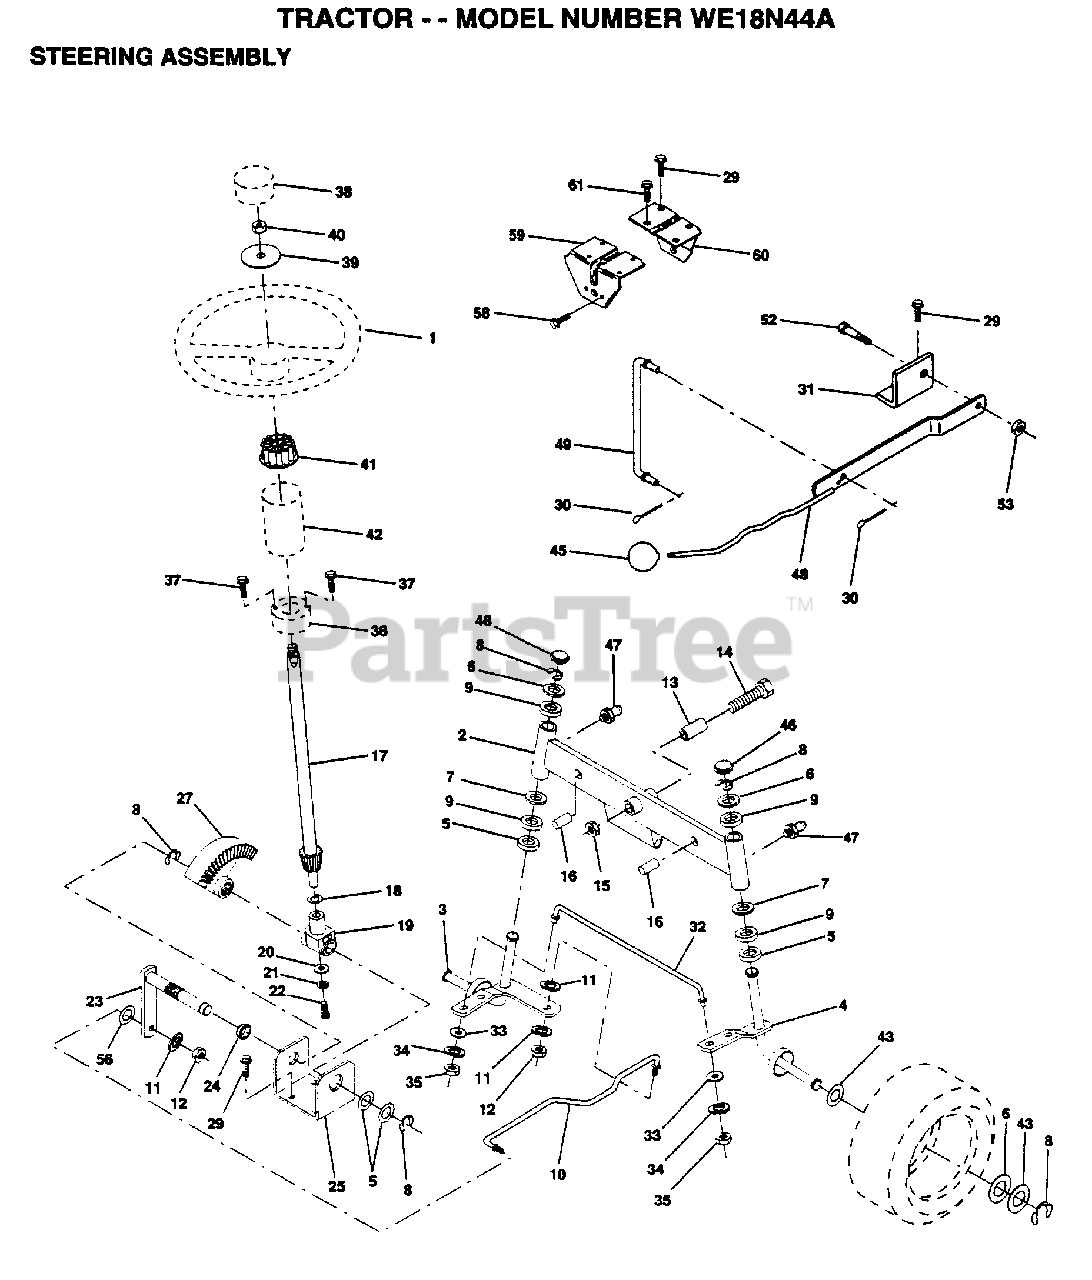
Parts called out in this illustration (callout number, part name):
2	AXLE ASM FRONT
5	WASHER .T
6	WASHER
7	WASHER
8	RING
9	COL. SRTG. BEAR.
11	LOCKWASHER
13	BEARING
14	BOLT LT
15	"NUT-LOC,FLANGE LT"
16	AXLE PIN
17	STEERING SHAFT
18	THRUST WASHER
19	SUPPORT.SHAFT
21	LOCKWASHER
22	"SCREW,SPECIAL"
24	NYLINER T
25	"BRKT,STEERING"
27	GEAR SECTOR
29	SCREW
30	COTTER PIN
31	BRKT.PVT.MAN.LVR.
32	ROD.TIE.19.75
33	WASHER M
34	LOCKWASHER
35	NUT.LOCK.5/16-24
36	BUSHING.STRG.3/4
37	SCREW.10-24X1/2
38	ST WHL INSERT CAP
39	WASHER
41	ADAPTER LT
42	BOOT SHAFT STEER
43	WASHER
45	KNOB T (1/2-HOLE)
46	CAP
47	ZERK M
48	LEVER.CLUTCH.MOWR
49	LINK CLTCH W/NUTS
52	"BOLT, SHOULDER LT"
56	WASHER
58	SCREW LT
59	SUPPORT-SADDL T
60	SUPPORT.SADDLE.FT
61	SCREW SPECIAL
